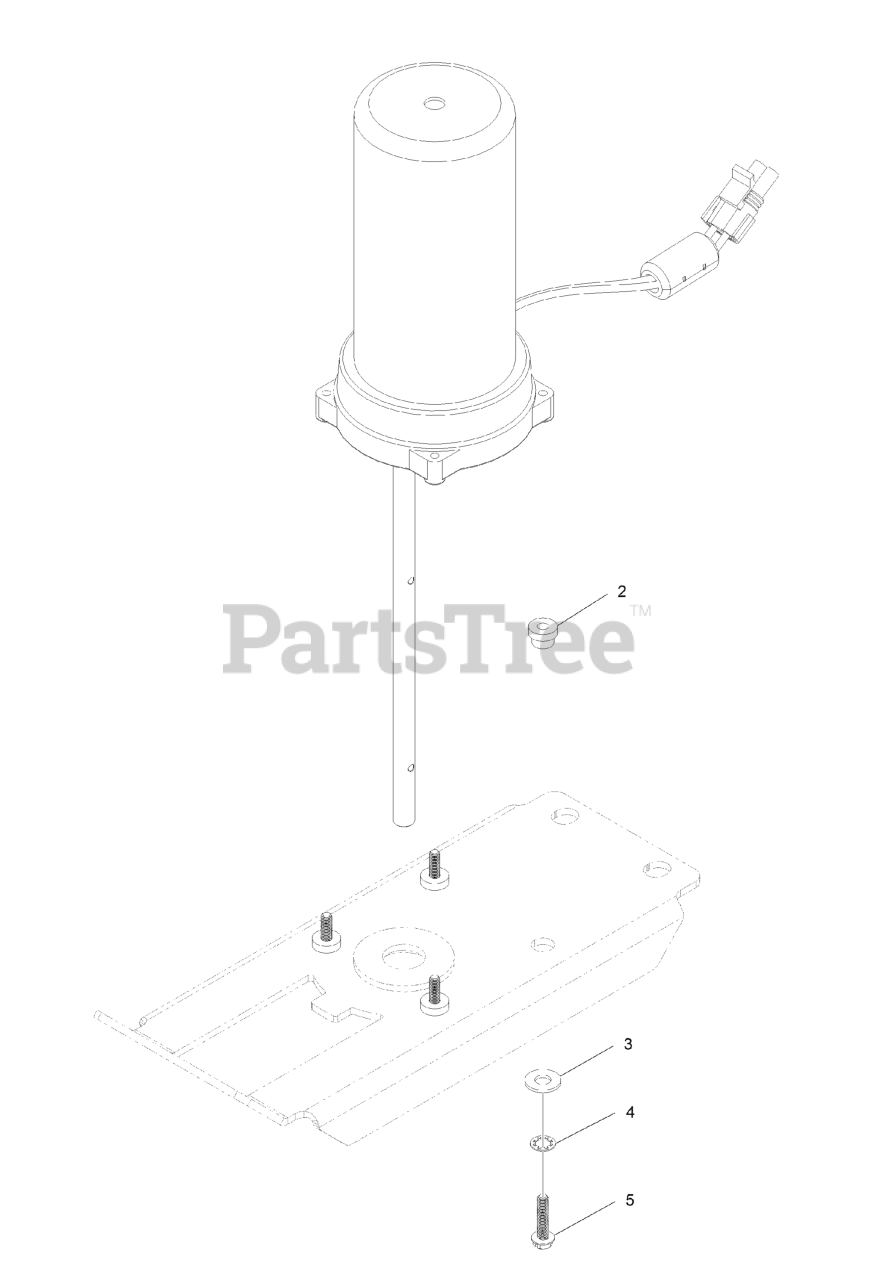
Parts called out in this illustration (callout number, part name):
2	SPACER-FLANGED
3	WASHER-FLAT
4	WASHER-LOCK, INT
5	SCREW-SHWH
